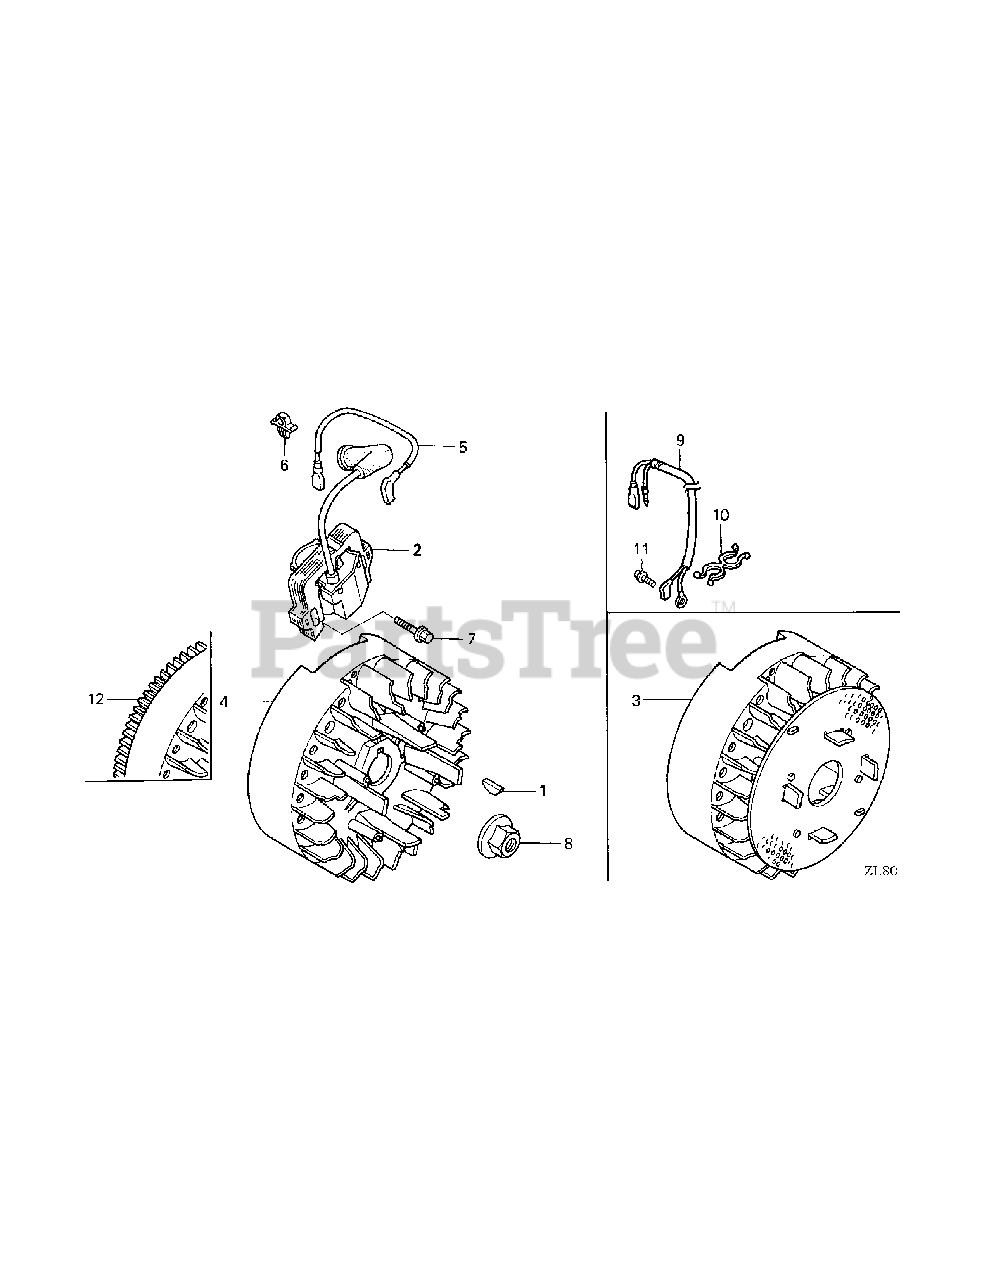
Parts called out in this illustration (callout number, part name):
1	Special Woodruff Key, 25 x 18
2	Ignition Coil Assembly
5	Stop Switch Wire
6	Stop Switch Wire Holder
7	Flange Bolt, 6 x 20
8	Special Nut, 14mm
